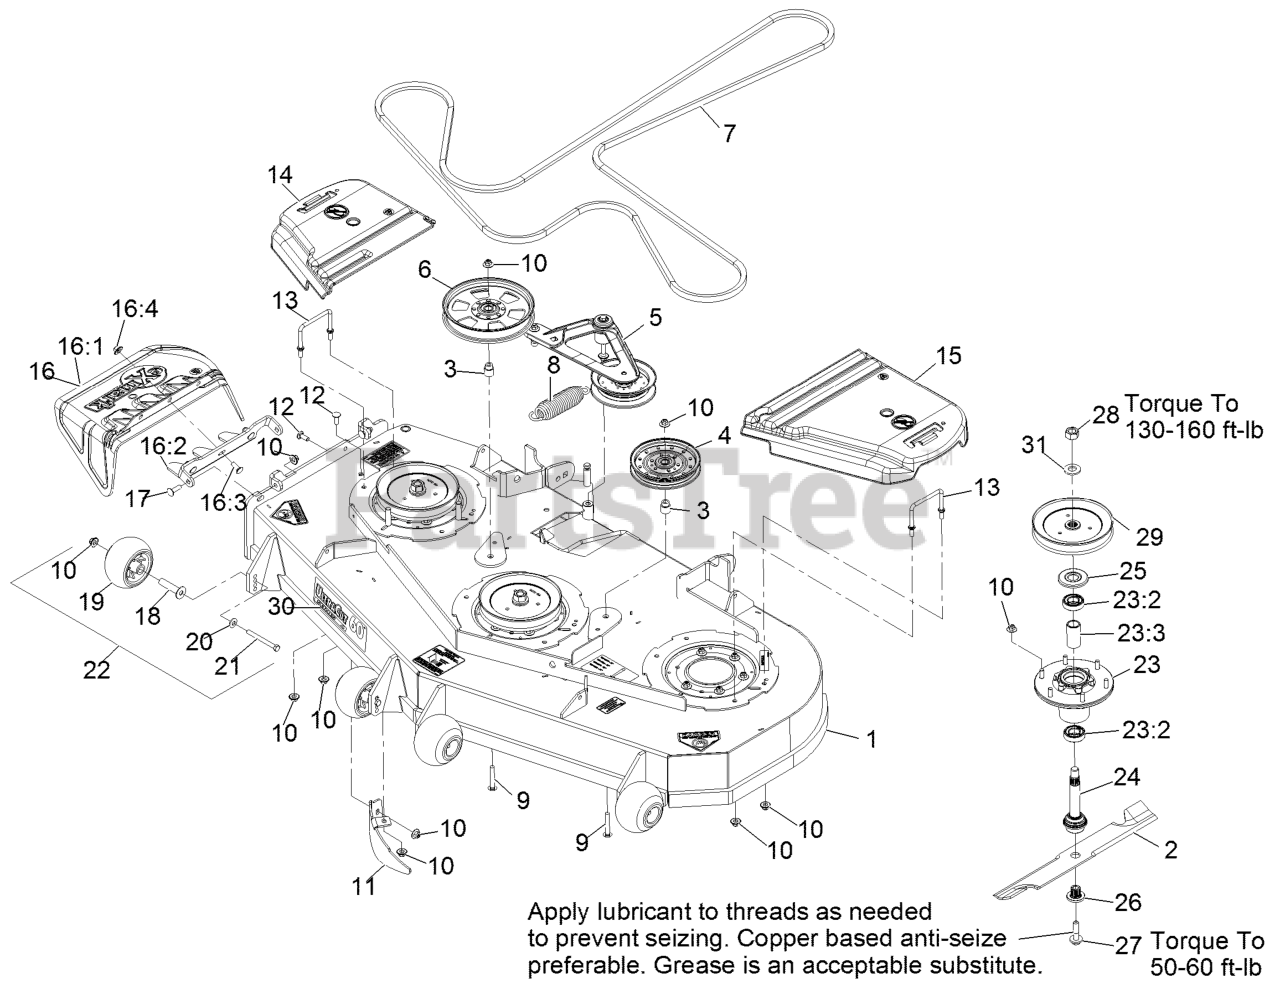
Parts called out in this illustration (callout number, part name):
1	DECK ASM,W/DECALS 60
2	Blade-Extreme 2, 20.50"
3	BUSHING-IDLER
5	DECK IDLER ASM
6	PULLEY-IDLER, FLAT
7	BELT,V-5V-198.75
8	SPRING-EXTENSION
9	SCREW-CARR
10	Nut-Nyloc 3/8-16 Flg
11	DOGLEG - LZ60
12	SCREW-CARR
13	WIREFORM-COVER
14	COVER-BELT, RH
15	COVER-BELT, LH
16	ASM,DISCHARGE CHUTE
16:1	CHUTE,DISCHARGE
16:2	BRACKET,DISCHARGE CHUTE
16:3	SCREW-CARR
16:4	Nut-Nyloc 3/8-16 Flg
17	Bolt-Carriage 3/8-16 X 1 1/4
18	AXLE, ROLLER
19	ROLLER-SCALP, ANTI
20	WASHER-BELLEVILLE
21	SCREW-HH 3/8-16 X 3 3/4 GR 8
22	KIT, ANTI-SCALP ROLLER
23	ASM-CUTTER HSG WITH BEARINGS
23:2	BEARING-BALL
23:3	SPACER-BEARING
24	ASM-SPINDLE AND SEAL
25	GUARD,BEARING TOP .989
26	BUSHING,SPLINED
27	SCREW,SEMS 1/2-20 X 2.19
28	NUT-HEX
29	SHEAVE,BLADE DRIVE 7.25
30	DECAL,ULTRACUT 60 SERIES
